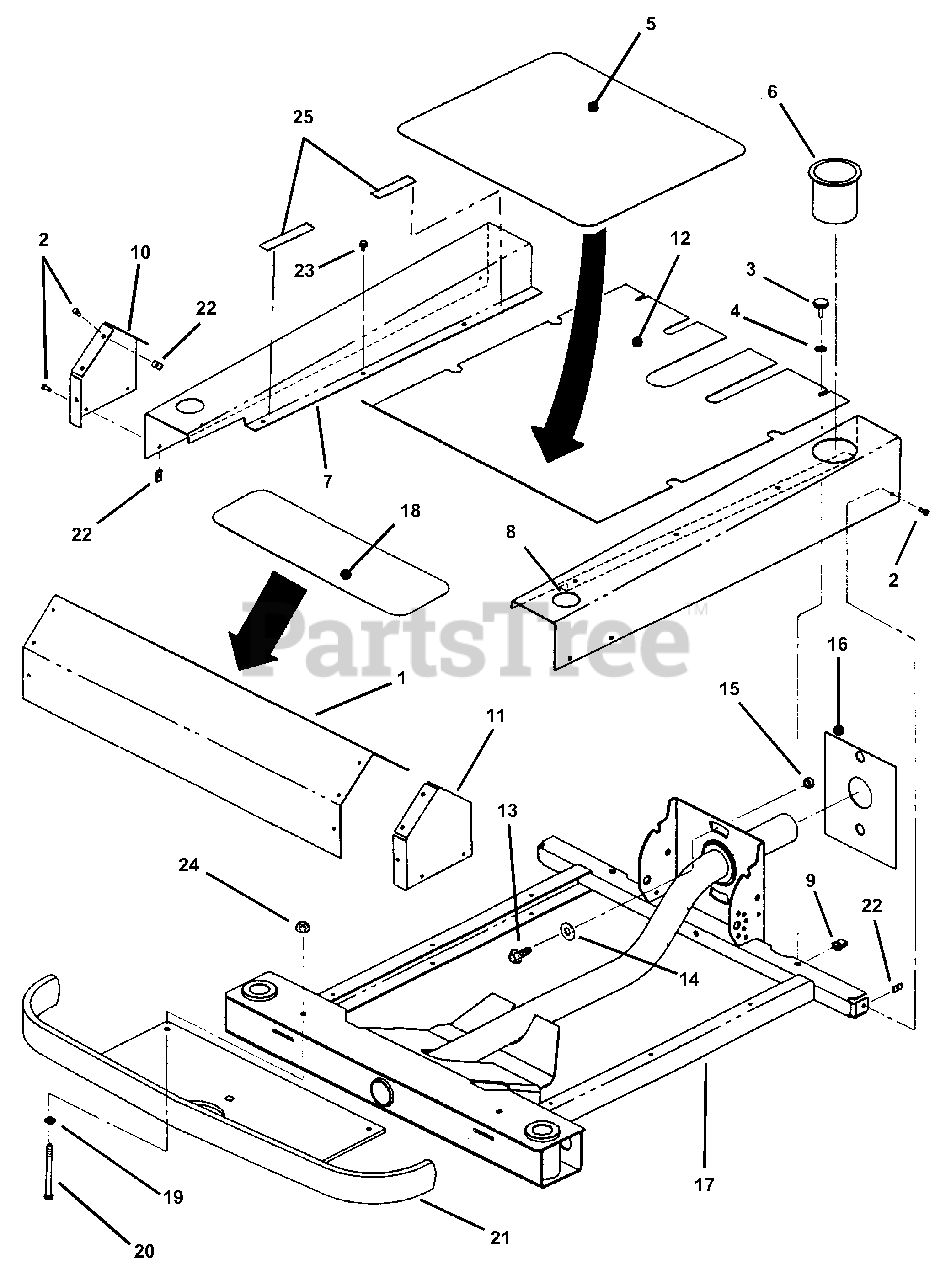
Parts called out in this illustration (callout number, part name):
1	FOOT REST
2	SCREW, #10-24 x 1/2" Hex Washer Self-Tap (Torx)
3	SCREW, 1/4-20 x 3/4" Thumb
4	WASHER, 1/4" Internal/External Lock
5	MAT, Floor
7	RAIL, Front Cover (Right Hand)
8	RAIL, Front Cover (Left Hand)
9	U-NUT, 1/4-20
10	PLATE, End (Right Hand)
11	PLATE, End (Left Hand)
12	PLATE, Floor
13	SCREW, 3/8-16 x 1" Hex Washer Face, Self-Tapping
14	WASHER, 3/8" Flat
15	SPACER, Front Frame Pivot
16	PLATE, Front Frame Pivot
17	FRAME, Front
18	PAD, Foot Rest
19	WASHER, 5/16" Split Lock
20	BOLT, 5/16-18 x 3-3/4"
21	BUMPER, Front
22	NUT, #10-24 Clip
23	SCREW, 1/4-20 x 3/8" Self-Tapping
24	NUT, 5/16-18
25	PAD, Floor Board Support
